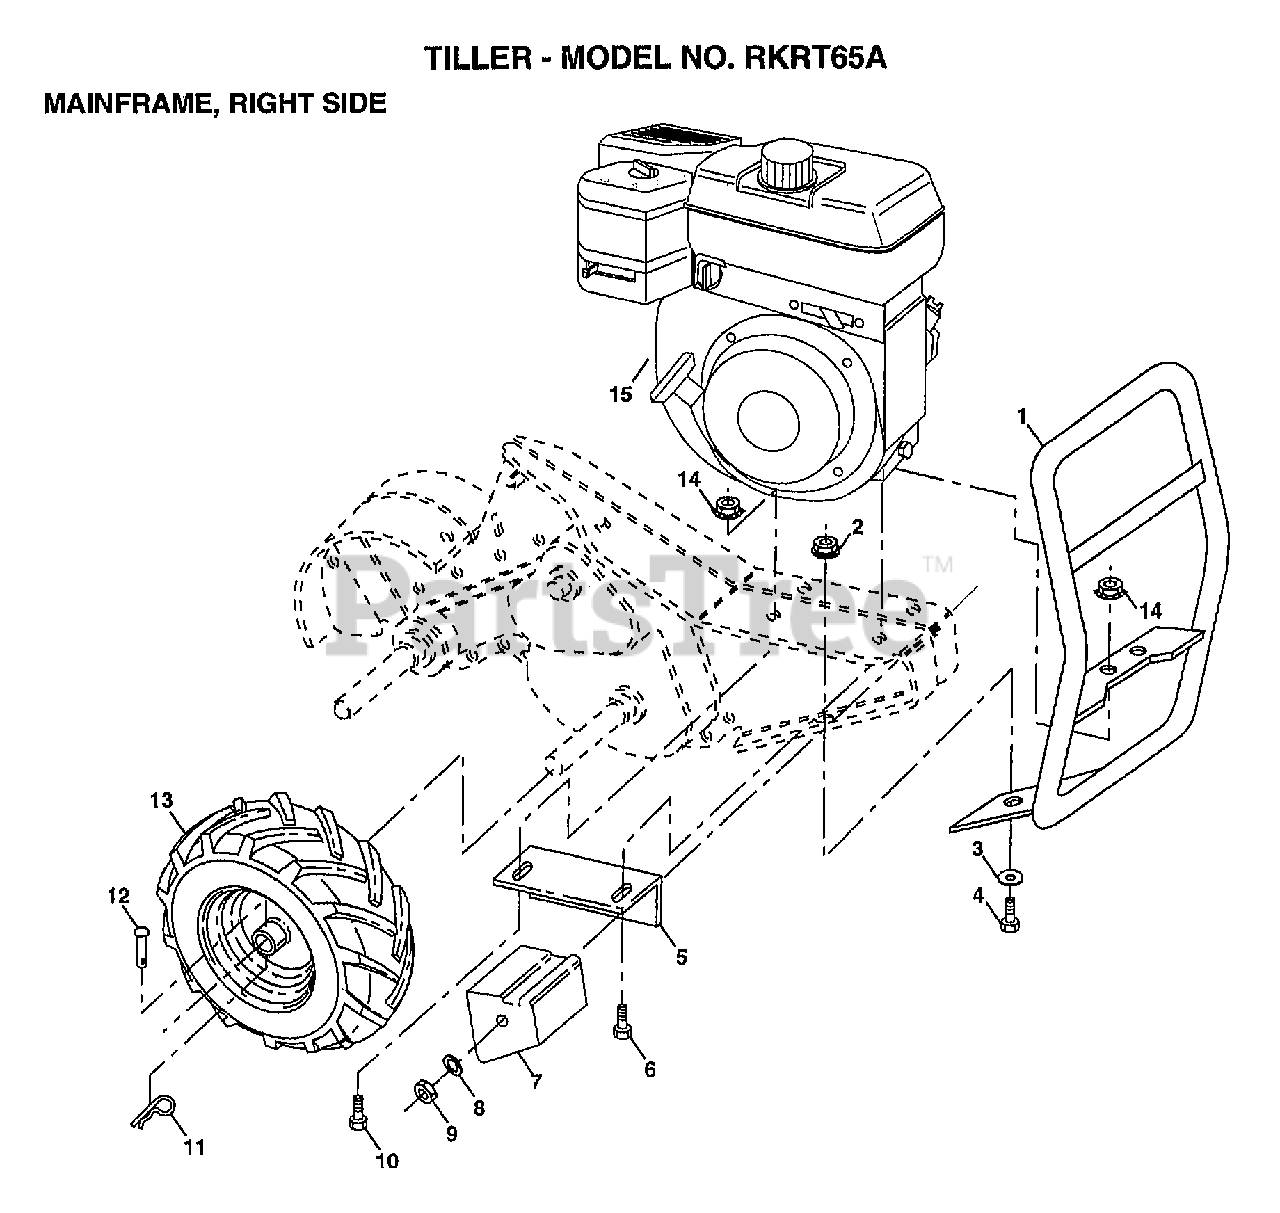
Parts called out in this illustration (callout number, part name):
1	BUMPER ASM.TILLER
2	LOCKNUT TI
3	WASHER
4	BOLT
5	BRACKET RH CRT
6	BOLT
7	COUNTERWEIGHT CRT
8	LOCKWASHER
9	NUT.HEX.3/8-16UNC
10	BOLT.HEX.5/16-1.5
11	RETAINER M
12	RIVET.DRILL.1.75
13	TIRE TI
13	RIM
